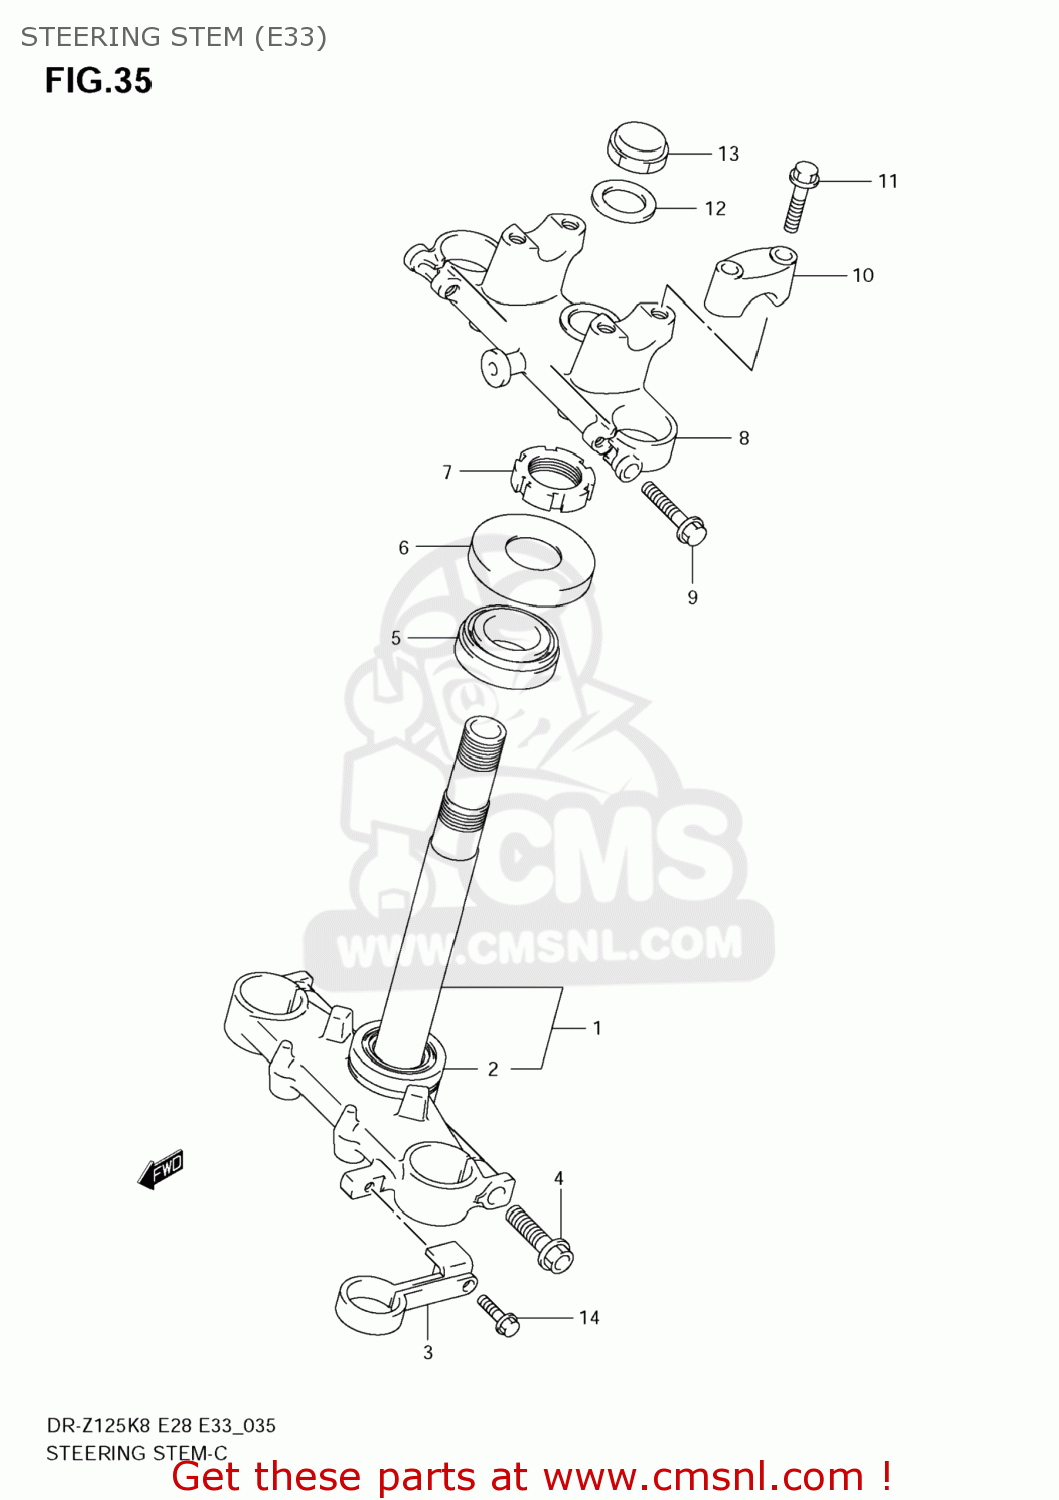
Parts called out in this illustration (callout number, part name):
1	STEM,STEERING
2	BEARING(26X47X15)
3	GUIDE,FR BRAKE HOSE
4	BOLT
5	BEARING(25X47X15)
6	SEAL,STEERING UPR DUST
7	NUT,STEERING
8	BRACKET,UPR
9	BOLT
10	HOLDER,HANDLE
11	BOLT
12	WASHER
13	NUT
14	BOLT
